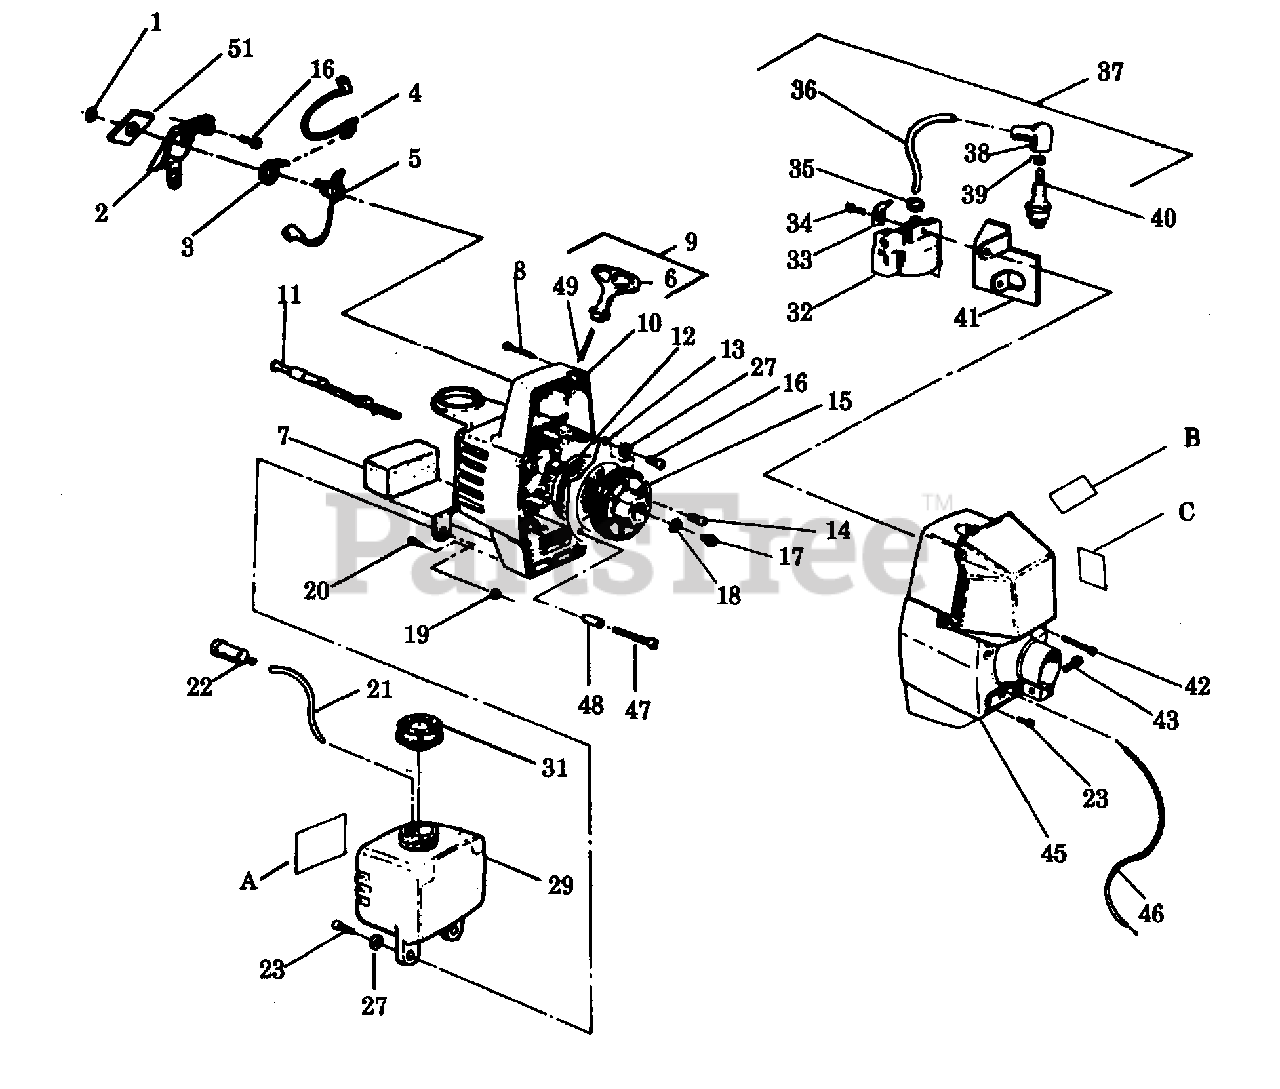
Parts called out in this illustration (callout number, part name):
1	Grounding Switch Nut
2	Housing Switch
4	Grounding Switch Lead Wire
5	Grounding Switch Kit (Inc.1,3,4,33)
6	Starter Handle
7	Air Filter
9	Rope and Handle Starter Ass'y. (Inc.6 & 49)
10	Fan Housing Kit
11	Choke Knob
12	Starter Pulley Spring
13	Air Baffle
15	Starter Pulley
17	Screw
21	Line Kit
22	Fuel Pick-Up Ass'y.
29	Fuel Tank Ass'y. (Inc.21,22,31)
31	Fuel Cap Ass'y.
32	Ignition Module Kit
33	Electrical Tab
34	Screw
35	Plug Wire Grommet
36	High Tension Lead Wire
37	High Tension Lead Ass'y.
38	Spark Plug Boot
39	Spark Plug Connector
40	Spark Plug (CJ-14)
41	Air Deflector
45	Shroud/Heat Shield Ass'y.
46	Throttle Cable
49	Rope Kit
51	Indicating Switch Plate
A	Fuel Tank Decal
B	Starting Inst. Decal (Not a serviceable part)
C	Shroud Decal (Left) (Not a serviceable part)
